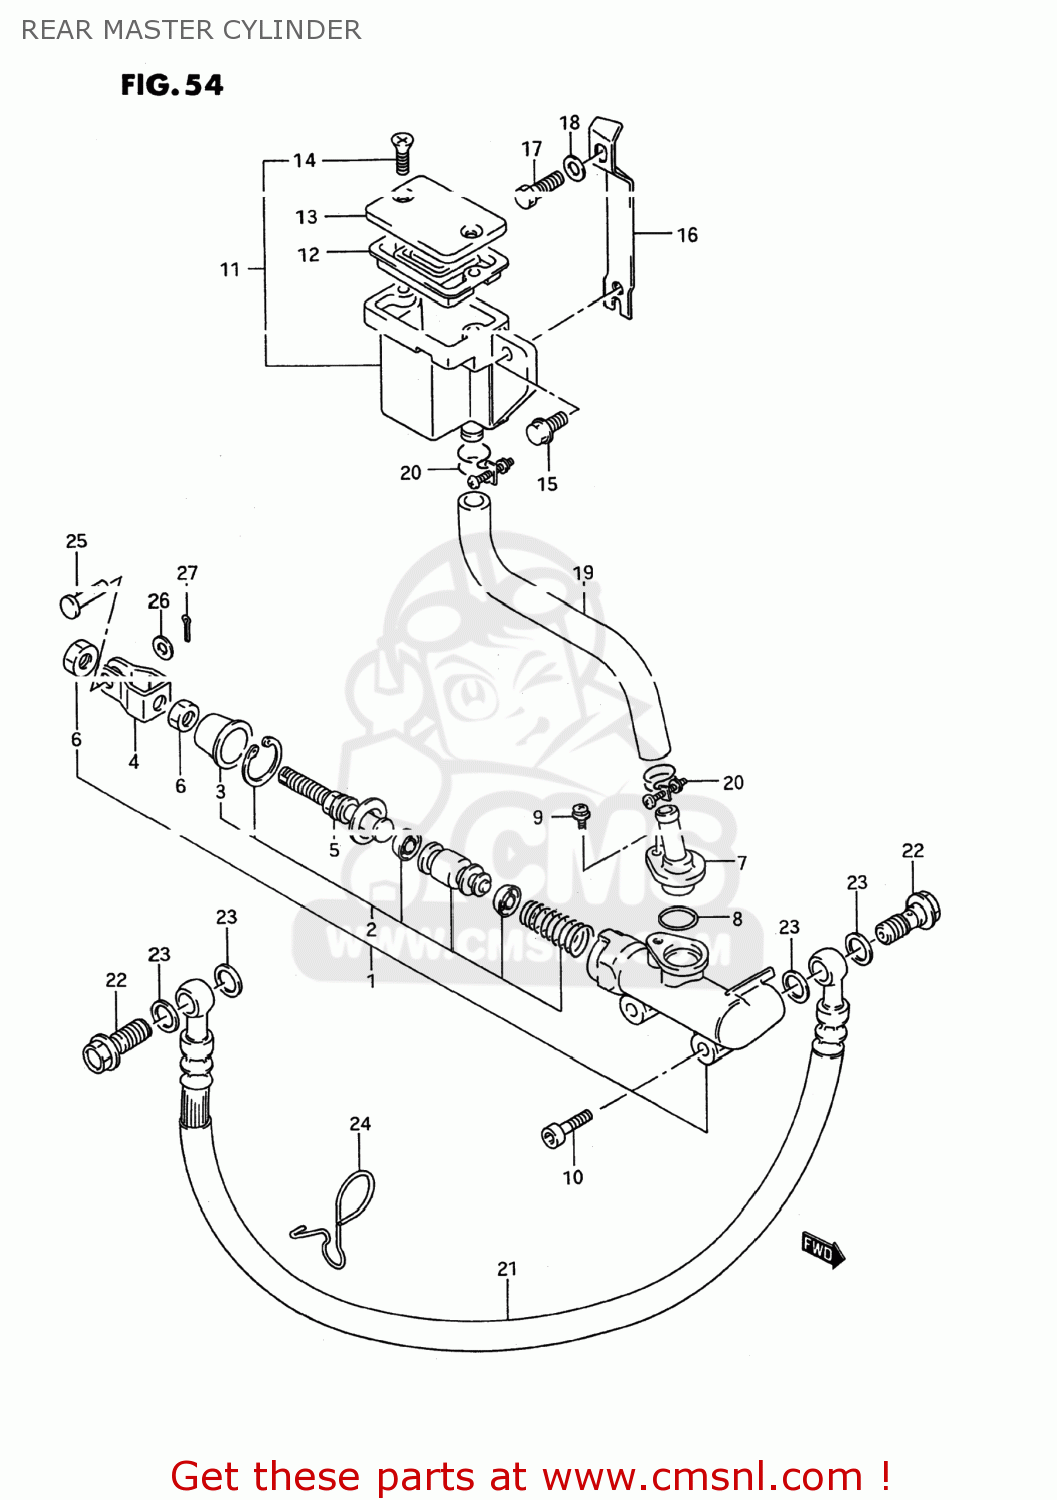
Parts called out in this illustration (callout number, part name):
1	CYLINDER ASSEMBLY,REAR MASTER
2	PISTON/CUP SET
3	BOOT
4	YOKE
5	ROD,PUSH
6	NUT
7	CONNECTOR
8	O RING
9	SCREW
10	BOLT
11	TANK ASSY,RESERVOIR
12	DIAPHRAGM
13	CAP
14	SCREW
15	BOLT
16	PLATE,RESERVOIR TANK
17	BOLT
18	WASHER,LOCK
19	HOSE,RESERVOIR TANK
20	CLIP
21	HOSE,RR BRAKE
22	BOLT UNION
23	WASHER(10X15X1.5)
24	GUIDE,BRAKE HOSE
25	PIN
26	WASHER
27	PIN
